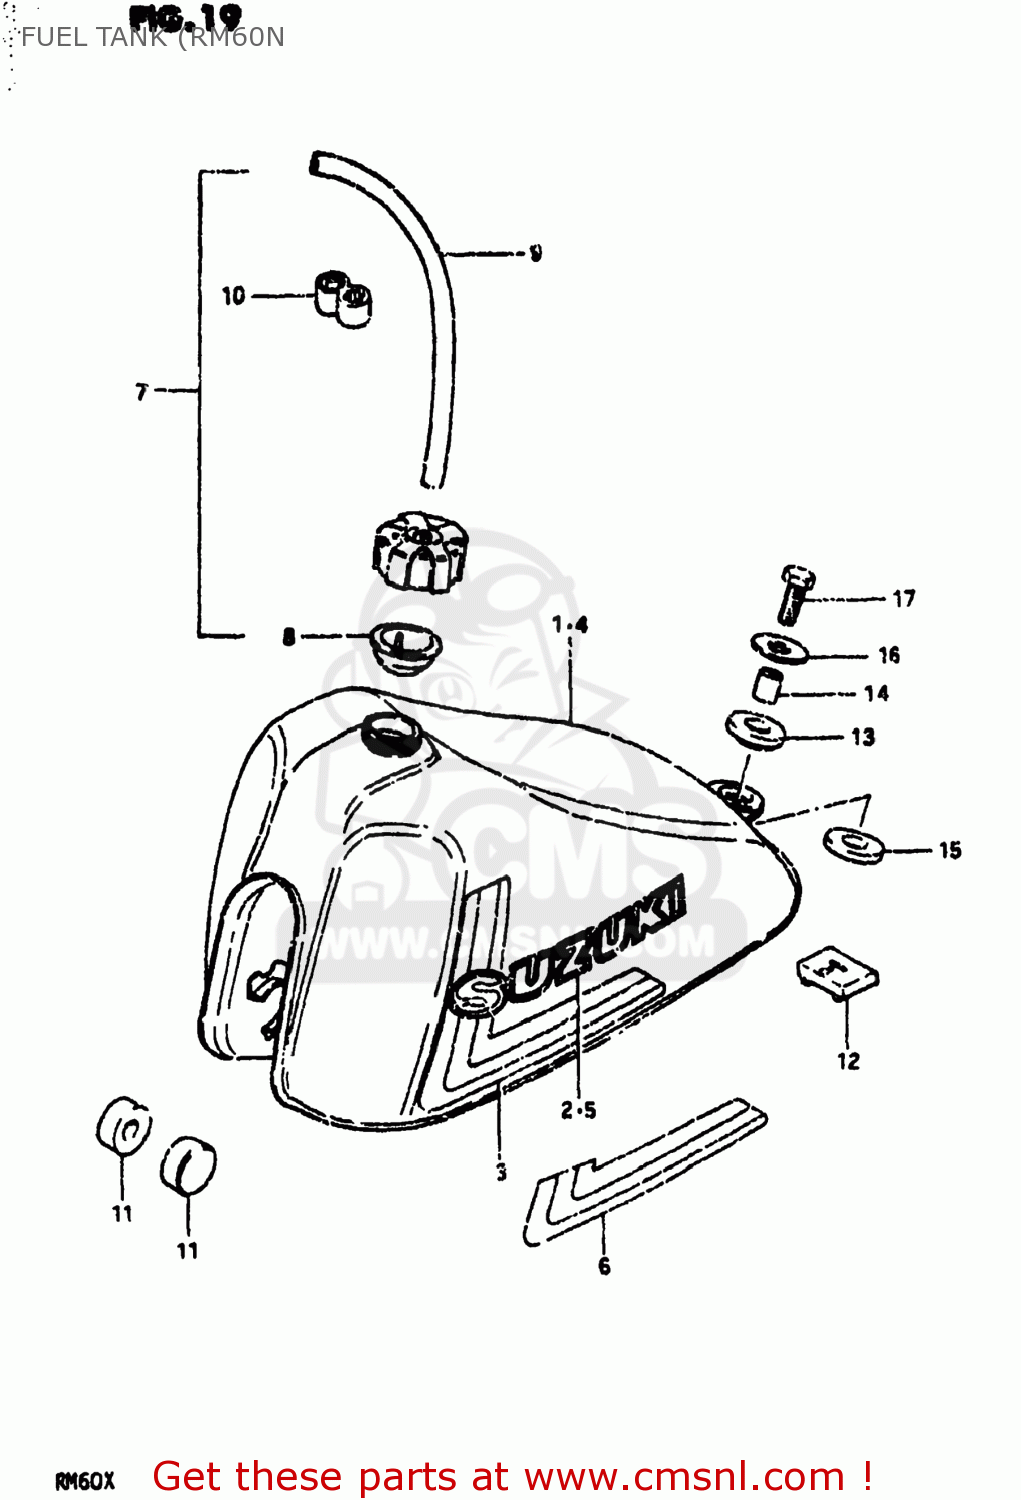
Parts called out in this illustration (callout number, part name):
1	TANK ASSEMBLY,FUEL
2	EMBLEM
3	TAPE SET
4	TANK ASSEMBLY,FUEL
5	EMBLEM
6	TAPE SET,FUEL TANK
7	CAP ASSEMBLY,FUEL TANK
8	GASKET,FUEL TANK CAP
9	HOSE
10	CLAMP,FUEL TANK BREATHER HOSE
11	CUSHION
12	CUSHION,FUEL TANK
13	CUSHION
14	SPACER (8.8X12X13.5)
15	CUSHION
16	BOLT
17	WASHER (8.5X29X1.6)
